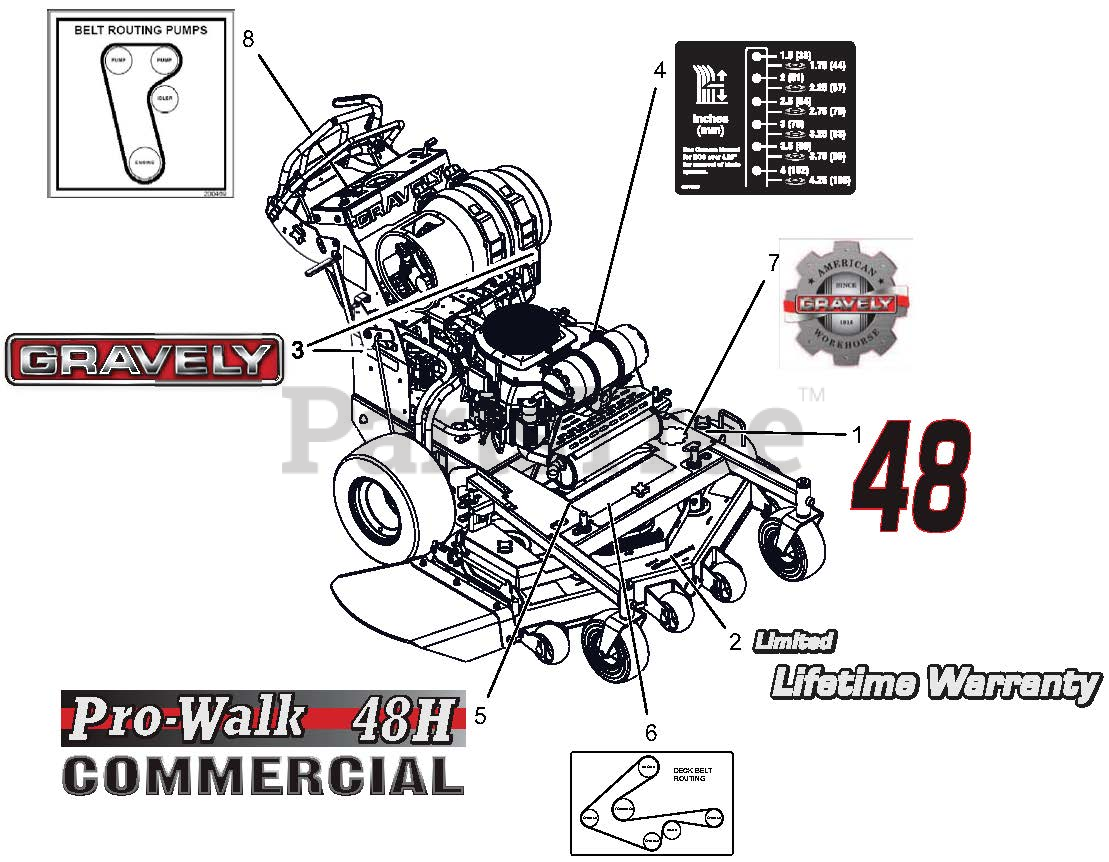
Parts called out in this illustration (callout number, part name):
1	DECAL, 48"
2	DECAL, LIMITED LIFETIME WARRANTY REV
3	DECAL, 6.5" GRAVELY LOGO
4	DECAL, PRO WALK HOC A
5	DECAL, PROWALK 48H
6	DECAL, BELT ROUTING 48/52 REV
7	DECAL, GRAVELY HERITAGE-LARGE
8	DECAL, PUMP BELT ROUTING
